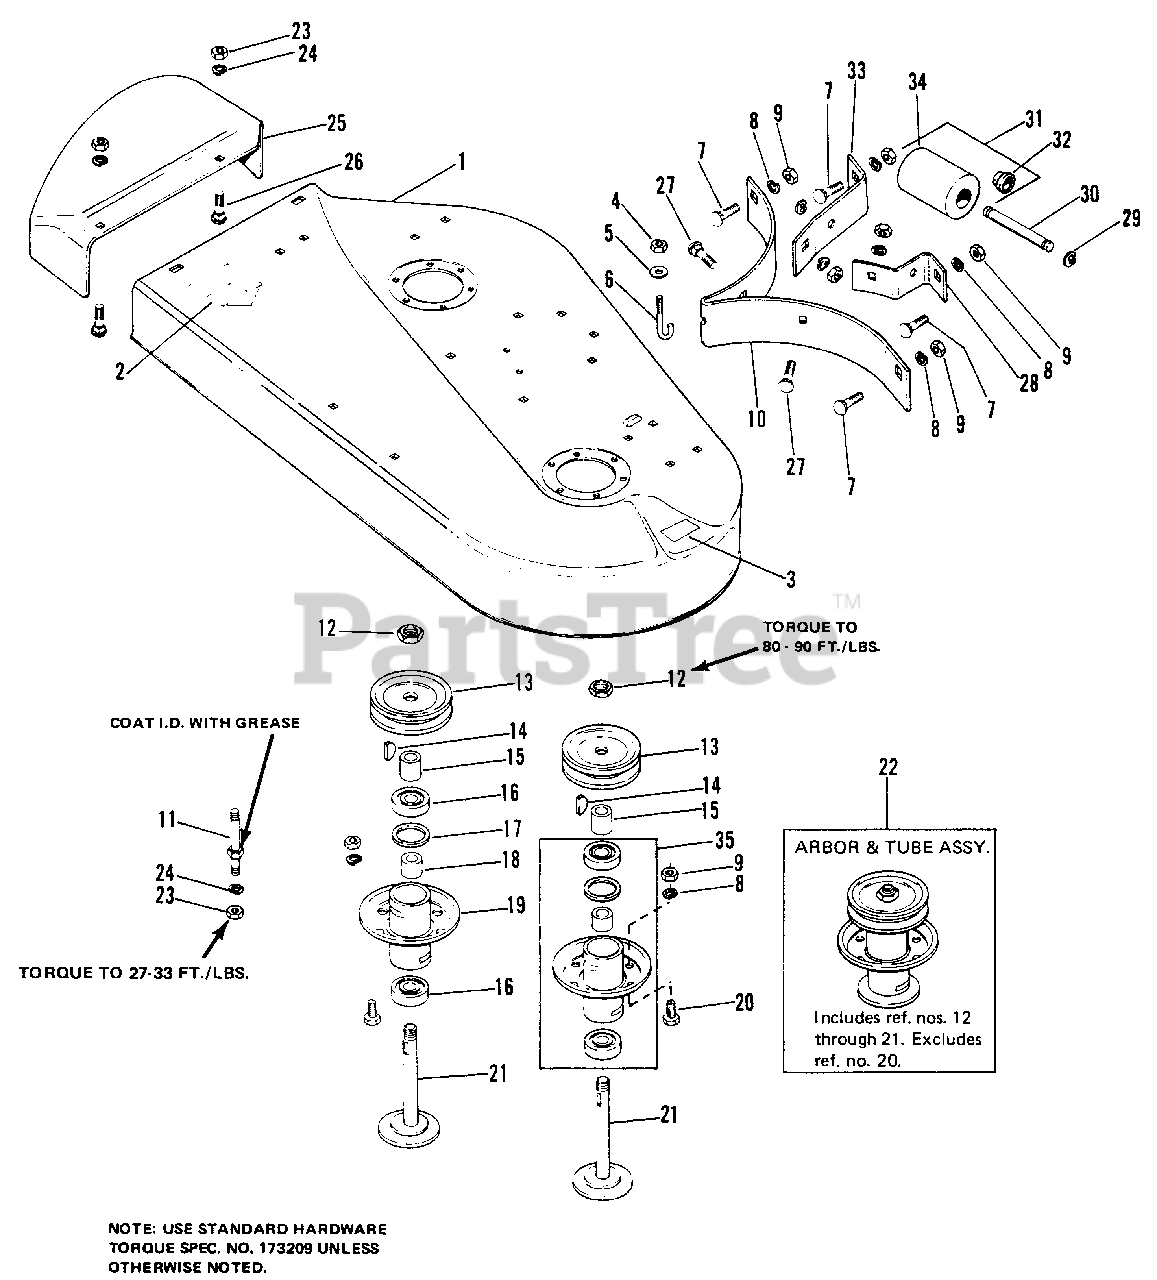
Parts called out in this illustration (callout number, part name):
1	DECK, Mower
2	DECAL, Caution, OPEI
3	DECAL, Caution
4	NUT, Hex, full, lock, 1/4-20
5	WASHER, Plain, 1/4
6	SCREW, Baffle hook
7	BOLT, Carriage, short neck, 5/16-18 x 3/4
8	LOCKWASHER, 5/16
9	NUT, Hex, full, 5/16-18
11	STUD, 2-5/8
12	NUT, Full, jam, 3/4-16
14	KEY, No. 61, Woodruff
16	BALL, Bearing
17	RING, Backing
19	ARBOR TUBE ASSEMBLY
20	CAPSCREW, 5/16-18 x 3/4
21	ARBOR ASSEMBLY
22	ARBOR & TUBE ASSEMBLY
23	NUT, Hex, 3/8-16
24	LOCKWASHER, 3/8
25	DEFLECTOR, Mower
26	BOLT, Carriage, 3/8-16 x 3/4
27	BOLT, Carriage, 5/16-18 x 5/8
28	BRACKET, L.H. Roller
29	RING,"E"
30	SHAFT, Center roller
31	ROLLER, .652 ID, 2.50 OD, 4.10 LG
33	BRACKET, R.H. Roller
35	TUBE & BEARING ASSY.
